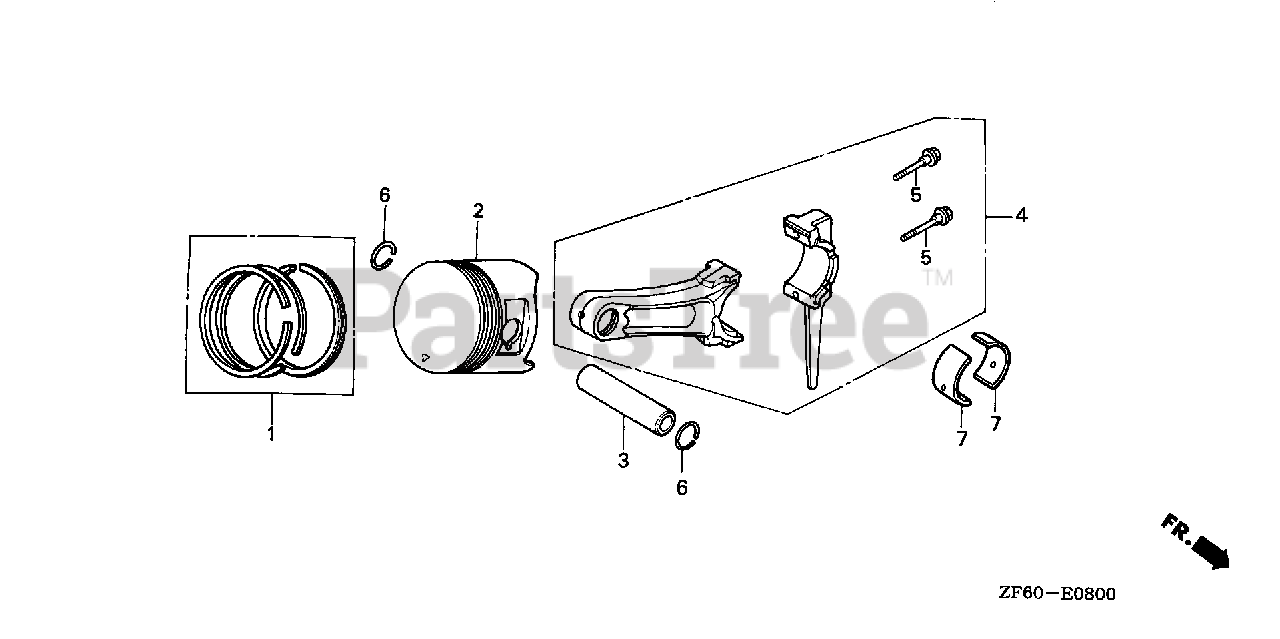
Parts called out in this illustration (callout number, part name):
1	RING SET, PISTON (STD) (NIPPON)
1	RING SET, PISTON (0.25) (NIPPON)
1	RING SET, PISTON (0.50) (NIPPON)
1	RING SET, PISTON (0.50) (TEIKOKU)
1	RING SET, PISTON (0.75) (NIPPON)
2	PISTON (STD)
2	PISTON (0.25)
2	PISTON (0.50)
2	PISTON (0.75)
3	PIN, PISTON
4	ROD ASSY., CONNECTING (STD)
4	ROD ASSY., CONNECTING (0.25 LOWER SIZE)
4	ROD ASSY., CONNECTING
5	BOLT, CONNECTING ROD
6	CLIP, PISTON PIN (20MM)
